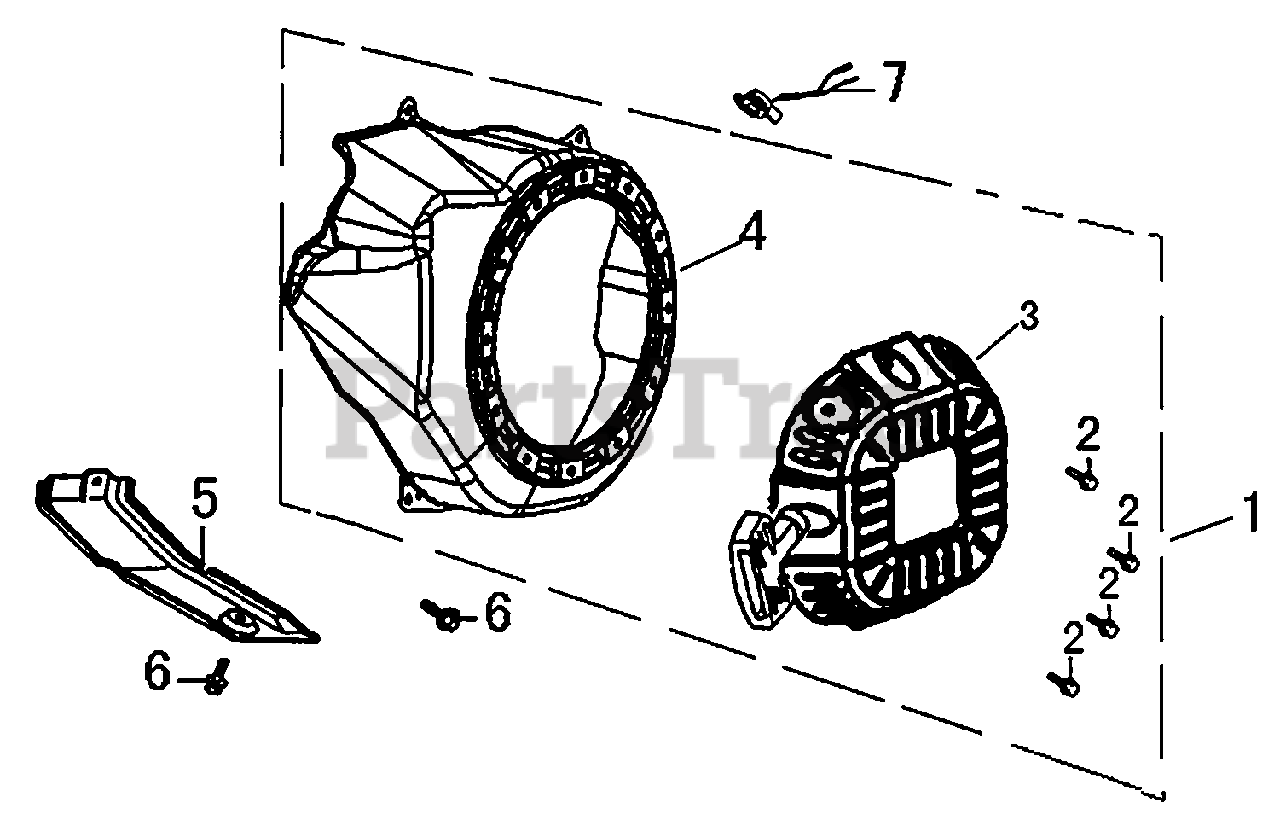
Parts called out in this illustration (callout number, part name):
1	STARTER, RECOIL W/BLWR HSNG
2	BOLT, FLANGE 6×8
3	STARTER ASSY.
4	COVER COMP., FAN
6	BOLT, FLANGE 6×12
7	SWITCH ASSY., ENGINE STOP
